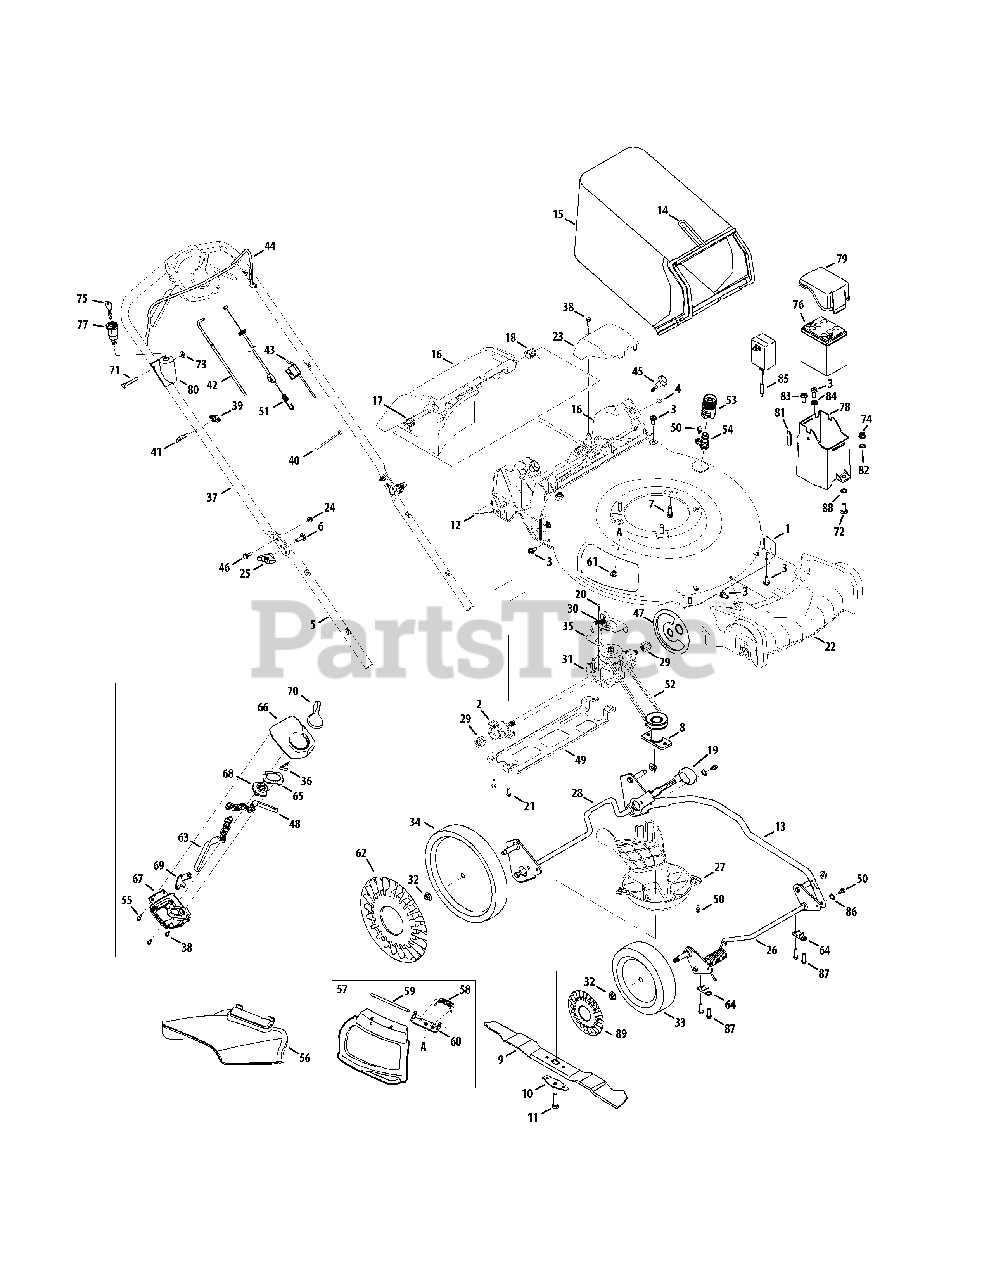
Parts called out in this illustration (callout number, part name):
1	21" Deck Ass’y
2	Bearing Assembly
3	Hex Hd. Cap Scr. 5/16-14 x .75
4	Sq. Nut 1/4-20
5	Lower Handle
6	Carriage Bolt 5/16-18
7	Hex Wash HD Tap Scr 3/8-16 x .88
8	Blade Adapter
9	21" Mulching Blade
10	Blade Bell Support
11	Hex Bolt 3/8-24 x 1.5" Lg. (Gr 8)
12	Trailing Shield 4.54 x 17.37
13	Cross Bracket
14	Catcher Frame
15	Grasscatcher Bag
16	Rear Baffle Ass’y (Incl. door)
17	RH Torsion Spring
18	LH Torsion Spring
19	Knob (Black)
20	Sems TT Scr. 1/4-20 x .50
21	Screw 1/4-15 x 1.25
22	Front Axle Cover
23	Transmission Cover
24	Flanged Lock Nut 1/4-20 Gr. F Nylon
25	Wing Knob-Black
26	Front Axle Ass’y
27	Engine Baffle
28	Rear Axle Ass’y
29	Spur Gear 9T
30	Extension Spring 2.405
31	Transmission Ass’y
32	Flange Locknut 3/8-16 Gr. F Nylon
33	Front Wheel
34	Rear Wheel
35	Transmission Bracket
36	Spring
37	Upper Handle - Black
38	Screw, 1/4-15 x .750
39	Knob 1/4-20
40	Cable Tie
41	Rope Guide Bolt
42	Drive Cable
43	Control Cable (B&S)
44	Blade Control
45	Knob 1/4-20 x 1.73 Black
46	Shoulder Screw .375 x .126 x 1/4-20
47	Dust Cover
48	Control Lever LH
49	Rear Support Bracket
50	Shoulder Scr. 1/4-20 x .50
51	Speed Adjustment Cable
52	V Belt
53	Water Nozzle Adapter
54	Deck Water Nozzle
55	Shoulder Screw 1/4-15 x .970
56	Chute Deflector
57	Mulching Plug Ass’y (Incl. ref. no. 58-60)
58	Torsion Spring
59	Hinge Pin
60	Chute Deflector Bracket
61	Screw 1/4-20 x .50
62	Hub Cap
63	Control Lever RH
64	Bushing .505 Dia. x .62
65	Cable Adjust Plate
66	Upper Housing
67	Lower Housing
68	Speed Adjust Actuator
69	Hub Cap 8"
70	Speed Select Lever
71	Hex. Hd. Cap Scr. 1/4-20 x 1.75 Gr. 5
72	Carriage Bolt 5/16-18 x 1.0
73	Hi -Lo Scr. 5/16-14 x .75
74	Hex Ins. L-Nut 5/16-18
76	Battery
77	Key Switch
78	Battery Housing
79	Battery Housing - Top
80	Switch Housing
81	Seal, Lid
82	Cupped Washer .340 x .872 x .060
83	Shoulder Screw 5/16-14 x .972
84	Spacer .340 x .460 x .246
85	Charger
86	Wave Washer
87	Screw 1/4-15
88	Speed Nut
89	Hub Cap 8"
